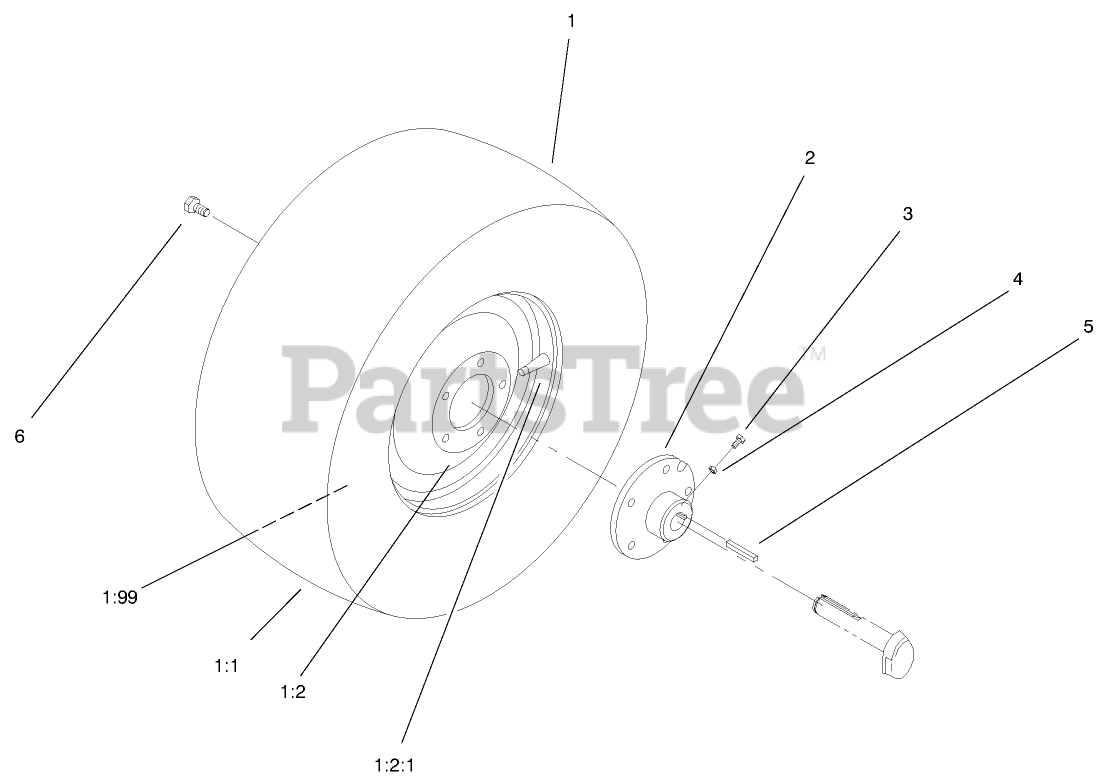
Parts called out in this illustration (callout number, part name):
1	Wheeltire ASM,Rear
1:2	WHEEL
1:2:1	VALVE
2	HUB-WHEEL
3	SCREW-SET, SQH
4	NUT-JAM
5	KEY-SQUARE
6	BOLT-LUG
